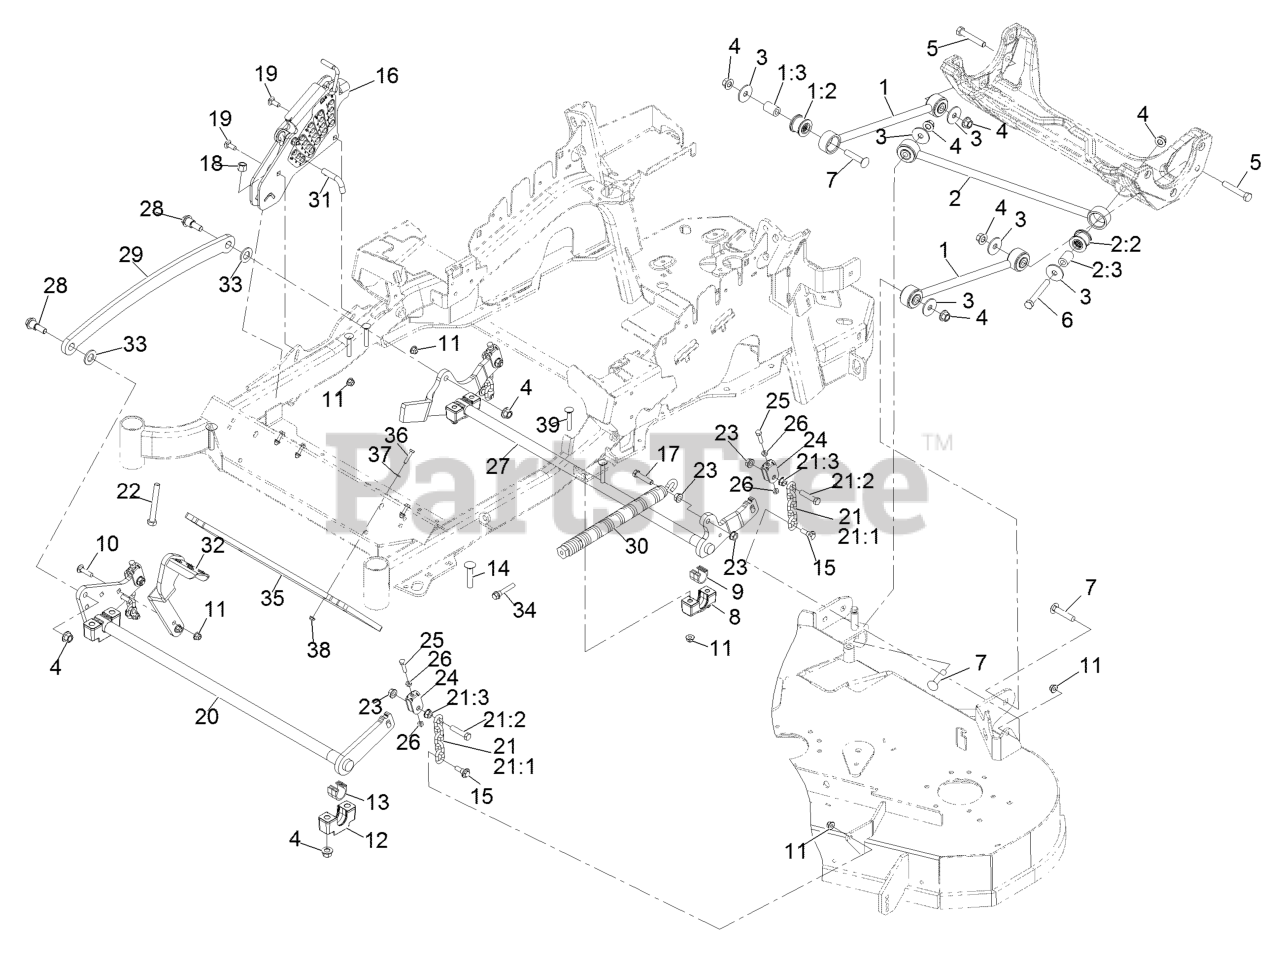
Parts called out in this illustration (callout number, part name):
1	DECK STRUT ASM
1:2	BUSHING-SUSPENSION, RUBBER
2	PANHARD ROD ASM
2:2	BUSHING-SUSPENSION, RUBBER
3	WASHER-THRUST
4	Nut-Lock 1/2-13
5	SCREW-HH
6	SCREW-HH
7	SCREW-CARR
8	SUPPORT-CROSS SHAFT, BEARING REAR
9	BEARING-CROSS SHAFT, REAR
10	SCREW-CARR
11	NUT-HF, NI
12	SUPPORT-CROSS SHAFT, BEARING
13	BEARING-CROSS SHAFT, FRON
14	Bolt-Carriage 1/2-13 X 2 1/2 Spl Neck
15	SCREW-SHOULDER, HHF
16	HOC ASM
17	SCREW-HH
18	NUT-LOCK, NI
19	BOLT-CARR
20	DECKLIFT-FRONT
21	DECK LIFT CHAIN ASM
21:1	CHAIN-LIFT, DECK
21:2	SCREW-HH
22	BOLT-TAP
24	YOKE-ADJUST, DECK
25	SCREW-HH
26	NUT-JAM
27	LIFT-DECK, REAR
28	SCREW-SHOULDER, HHF 1/2-13 X 1.12
29	LINK-LIFT, DECK
30	SPRING-EXTENSION
31	PIN-HOC
32	LEVER-FOOT
33	WASHER-FLAT
34	BOLT-SHOULDER
35	WEIGHT-TOE BOARD
36	SCREW-HH
37	WASHER-FLAT
39	Bolt-Carriage 3/8-16 X 2 1/4
